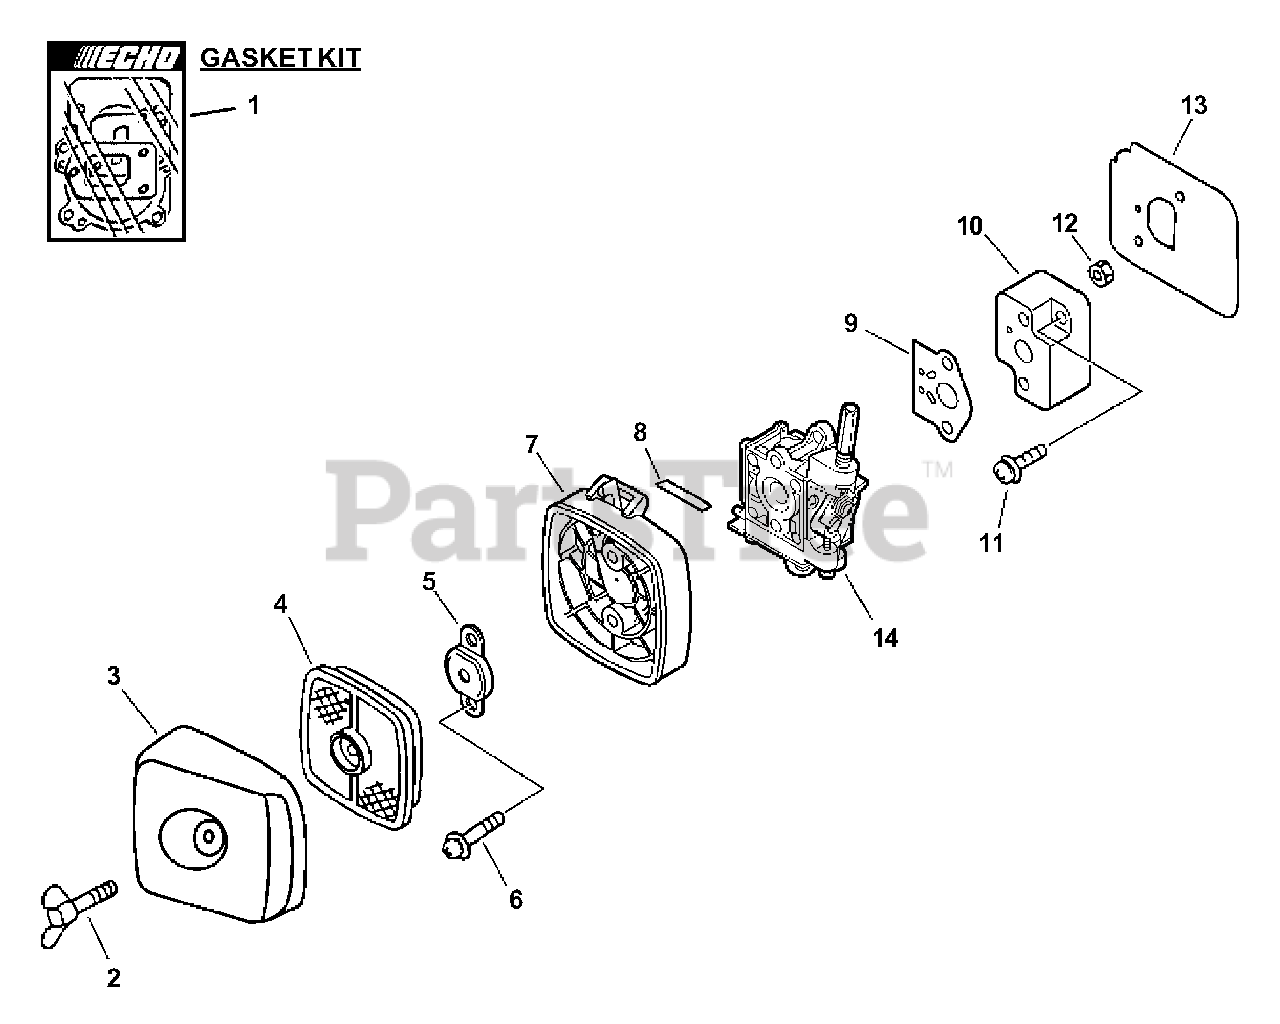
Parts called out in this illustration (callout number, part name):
1	GASKET KIT
2	THUMBSCREW
3	COVER, AIR FILTER - GRAY
4	FILTER, AIR - SINGLE LAYER
5	PLATE, PREVENT
6	SCREW - 5X65
7	CASE, AIR FILTER - GRAY
8	LABEL - CHOKE
9	GASKET, INTAKE
10	INSULATOR, INTAKE
11	SCREW - 5X20
13	SHIELD, INTAKE
14	CARBURETOR
